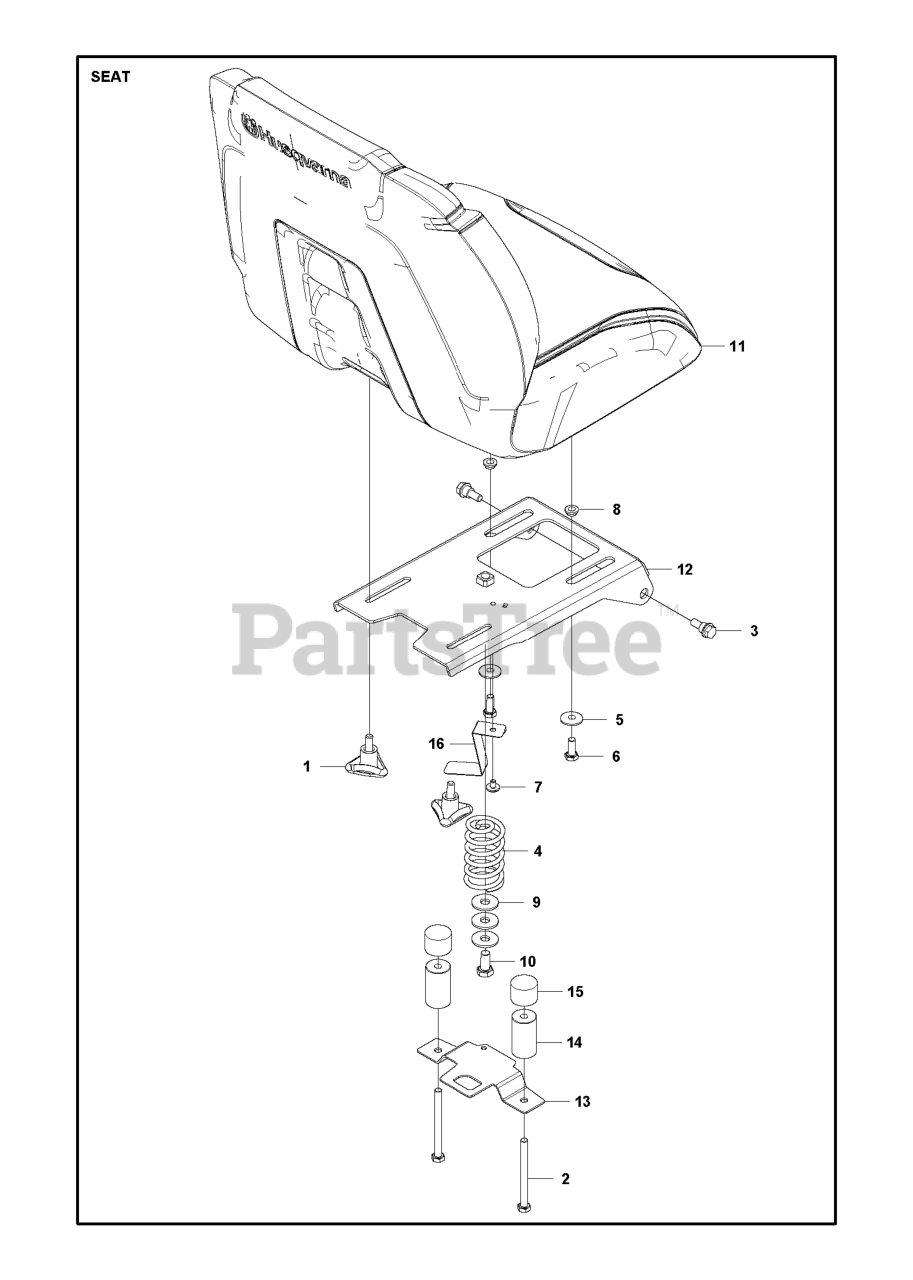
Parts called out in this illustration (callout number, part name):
10	Screw M10x25
11	SEAT HUSQVARNA HIGH BACK
15	ANTIVIBRATION ELEMENT
